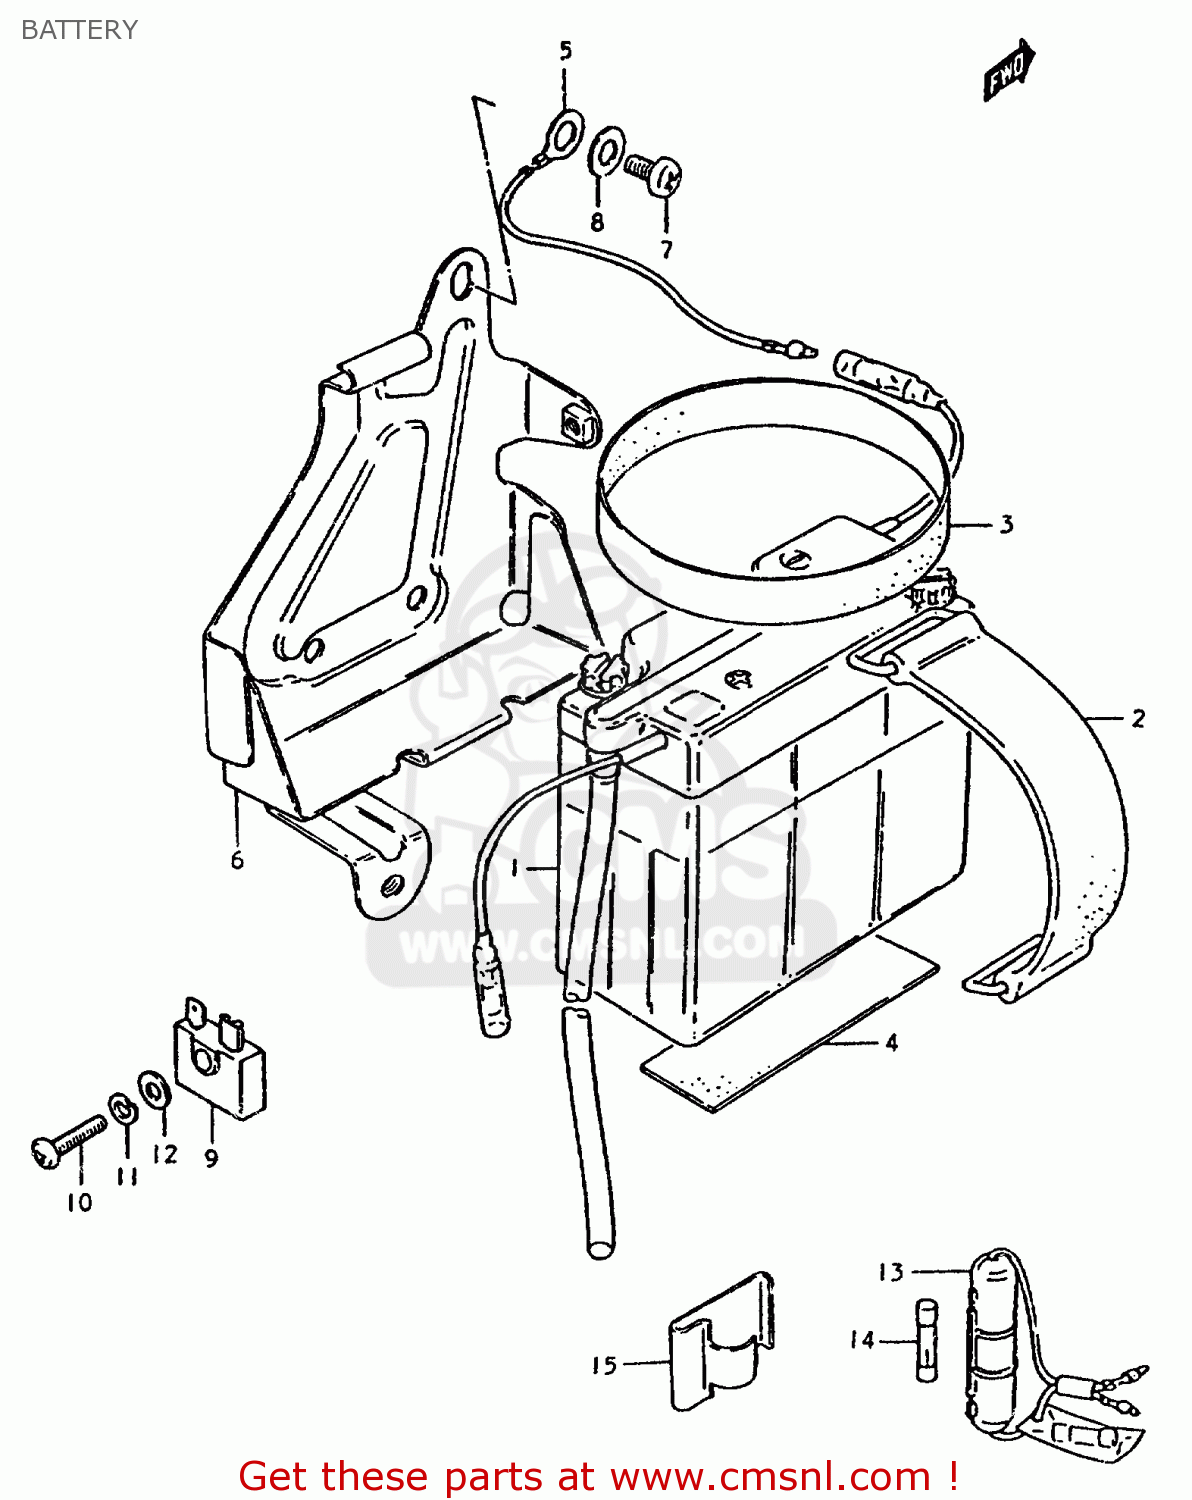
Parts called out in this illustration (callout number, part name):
1	BATTERY(6N4B-2A,6V4.2AH)
2	BAND
3	PROTECTOR,BATTERY
4	PROTECTOR(30X80X2)
5	LEAD WIRE
6	HOLDER, BATTERY
7	SCREW 6X12
8	WASHER
9	RECTIFIER ASSEMBLY
10	SCREW 5X20
11	LOCK WASHER
12	WASHER
13	BOX ASSEMBLY,FUSE
14	FUSE(10A)
15	HOLDER,FUSE CASE
